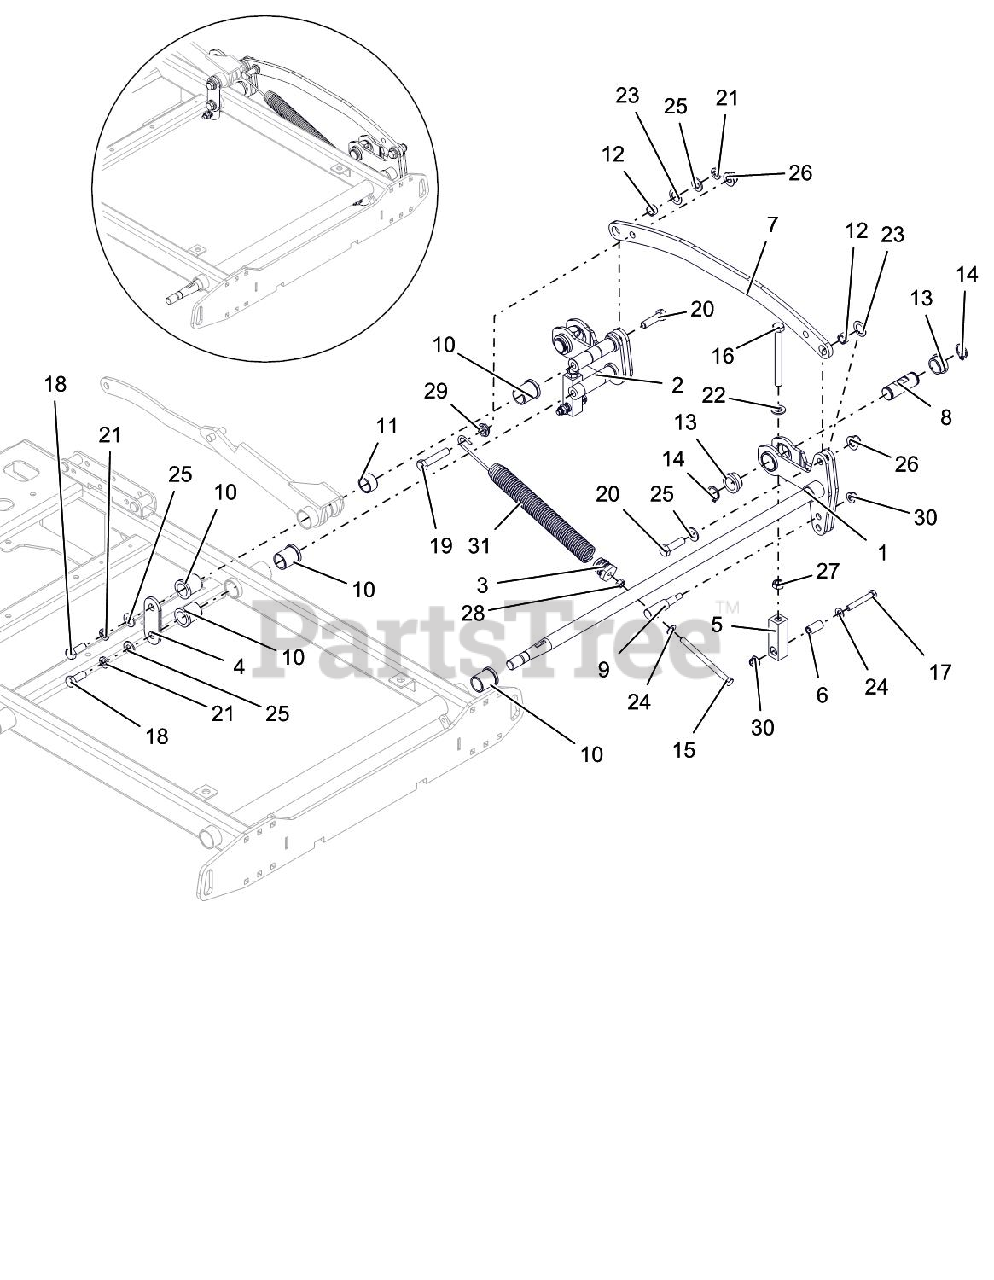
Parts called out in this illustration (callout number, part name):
1	WLDMT, PSTANCE TAPERED SHAFT
2	WLDMT, PSTANCE DECK ARM
3	PLUG, SPRING
4	PLATE, LIFT LINK ATTACH
5	LINK, DECK LIFT
6	SPACER, DECK LEVELING
7	ARM, DECK LIFT
8	PIN, DECK LIFT
9	TRUNION, DECK LIFT
10	BSHG-FLG 1.00X1.25X1.50X1.50
11	BUSH, SLV 1.00 X 1.25 X .75
12	BSHG-SLV .513 X .748 X .420
13	BSHG,FLG 1.0 X 1.25 X 1.5 X .6
14	RG-RTNG-EXT 1.00X.078
15	BLT-HEX .38-16X5.00 GR5 FTH YZ
16	BOLT, 1/2-13 X 5.0 2.5 THREAD
17	BLT-HEX .38-16X2.50 GR8 YWZC
18	@BLT-HEX .50-13X1.25 GR5 YWZC
19	@BLT-HEX .50-13X2.50 GR5 YWZC
20	@BLT-HEX .50-13X1.75 GR5 YWZC
21	@WSHR-LK .50X.125 REG YWZC
22	FLATWASHER 1/2 SAE HARD 15906
23	WSHR-HDND-THRST .758X1.23X.031
24	@WSHR-FL-STL.406X.812X.065 YWZ
25	@WSHR-FL-STL.531X1.06X.095YWZC
26	@NUT-LK-NYL-FLG .50-13 YWZC
27	NUT-JAM .50-13 YWZC
28	@NUT-HEX .38-16 YWZC
29	NUT-SPNLK-FLG .50-13 YWZC
30	@NUT-LK-NYL-FLG .38-16 YWZC
31	SPRING, DECK LIFT
